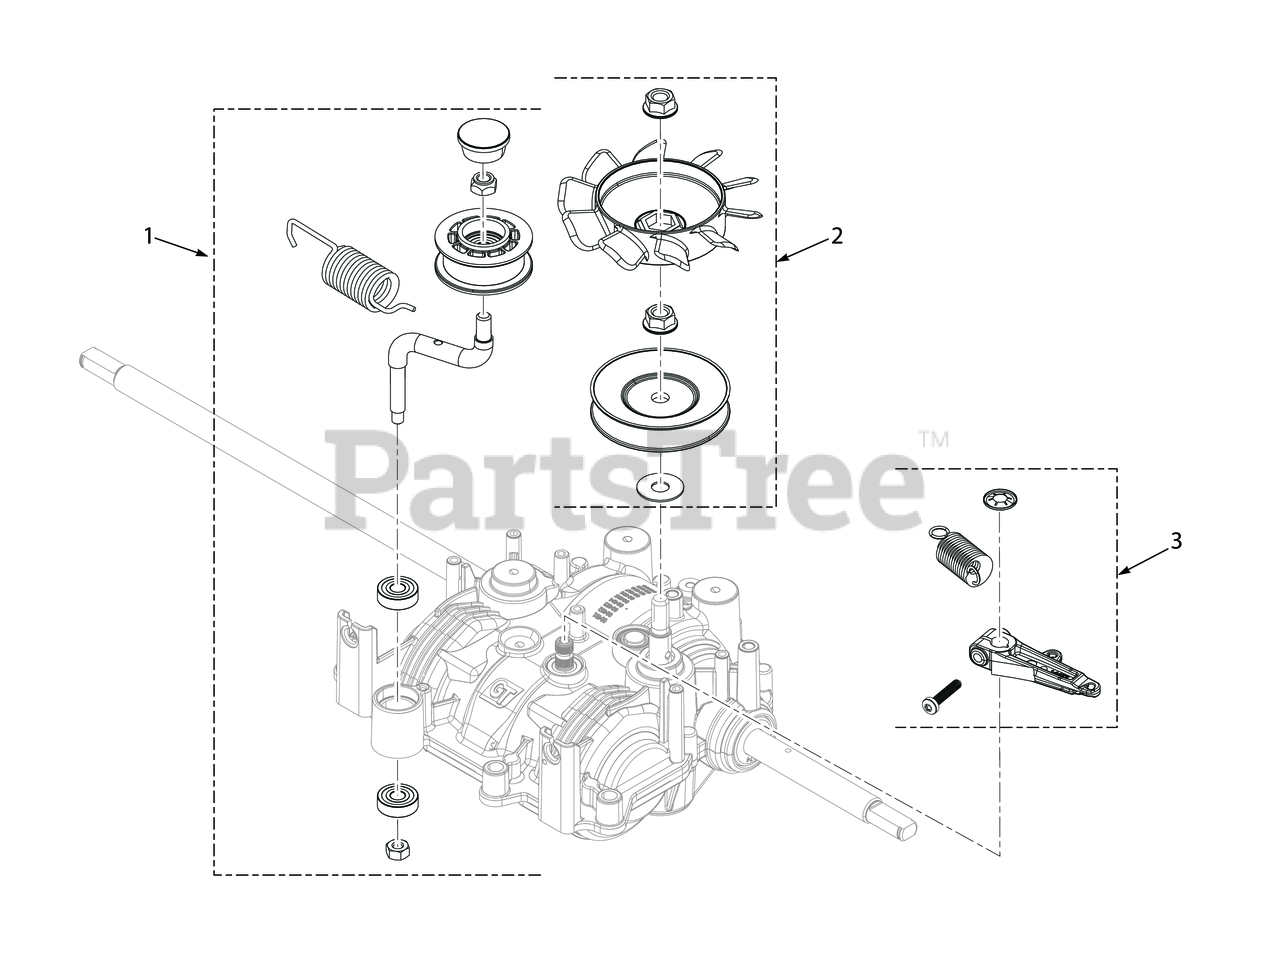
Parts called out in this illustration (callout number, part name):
1	Transmission Service Kit, Idler Assembly
2	Transmission Service Kit, Pulley & Fan Assembly
3	Transmission Service Kit, Clutch Lever Assembly
